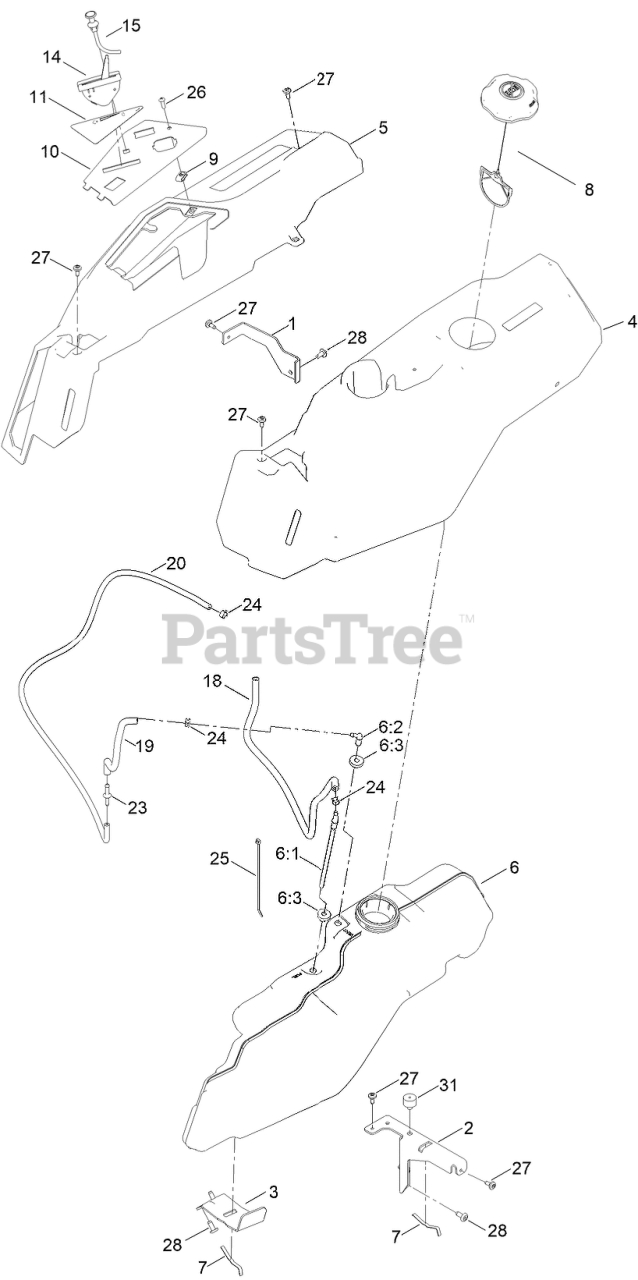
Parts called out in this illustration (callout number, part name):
1	BRACKET-POD
2	SUPPORT-POD, LH
3	SUPPORT-TANK, FUEL
4	POD-LH
5	POD-RH, MYRIDE
6	FUEL TANK ASM
6:1	CONNECTOR-ELBOW, 90 DEG
6:2	FITTING-PLASTIC
6:3	BUSHING
7	SPRING
8	CAP-FUEL, RATCHETING
10	PANEL - CONTROL
11	DECAL-PANEL, CONTROL
14	CABLE-THROTTLE
15	CABLE-CHOKE
18	HOSE-FUEL
19	HOSE-FUEL
20	HOSE-FUEL
23	ADAPTOR-ORIFICE
24	CLAMP-HOSE
25	TIE-CABLE
26	SCREW-PRH
27	SCREW-SHOULDER
31	BUMPER-GROMMET
